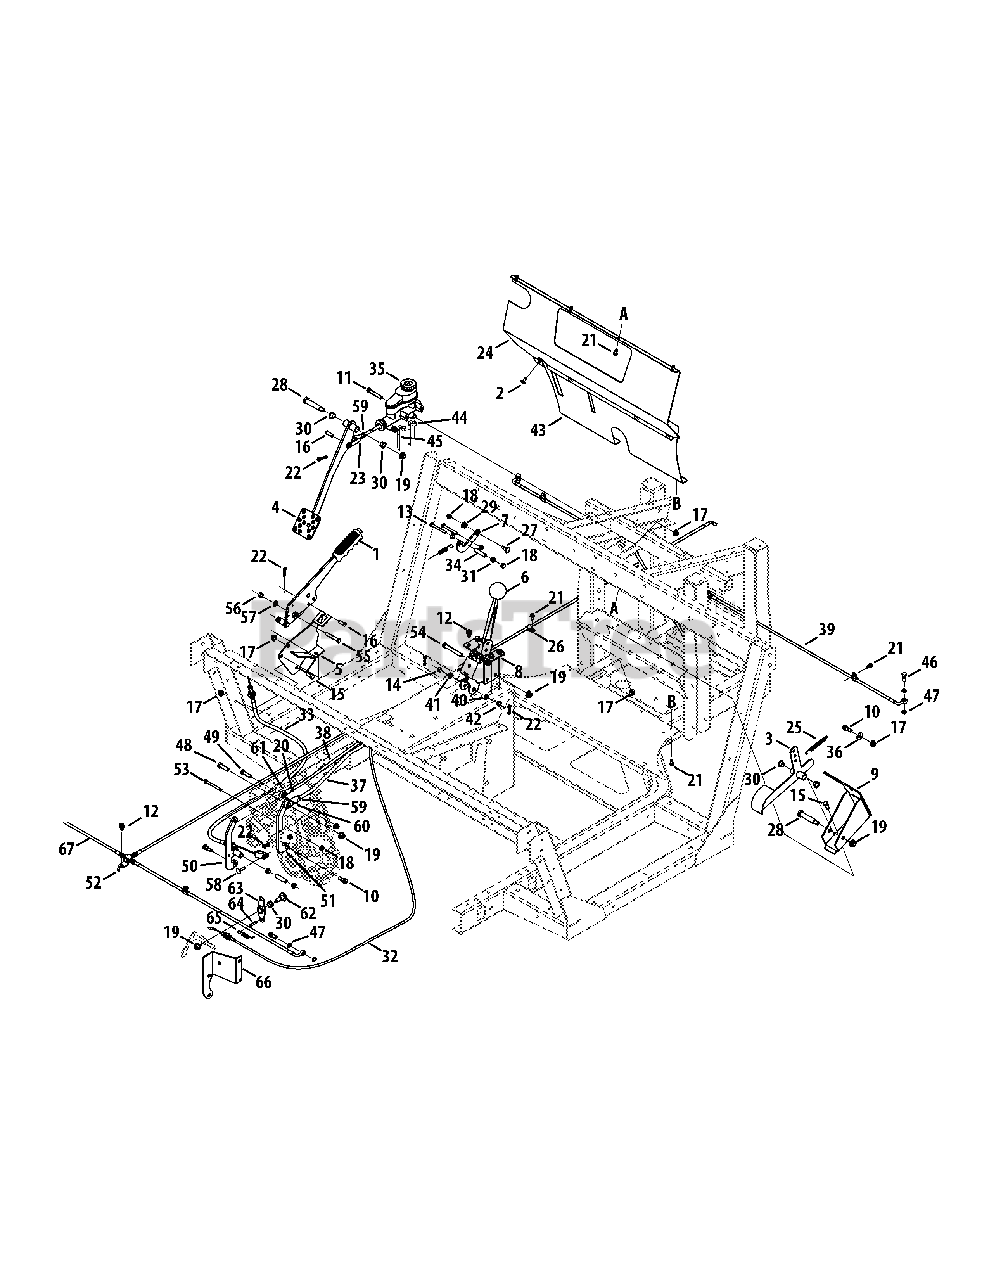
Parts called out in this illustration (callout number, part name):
1	Lever Assembly, Brake
2	Screw, ab, 1/4-14, 0.625,
3	Pedal Assembly, Accelerator
4	Pedal Assembly, Brake
5	Bracket Assembly, Park Brake
6	Shaft Assembly, Hurst, 4x4
7	Plate, Pawl, Over Center
8	Shaft, Console Mount
9	Bracket, Accelerator Pedal
10	Screw, Shldr, .372 x .375, 5/16-18
11	Screw, 5/16-18, 2.00, Gr5, Patch
12	Screw, Tt, 5/16-18, 0.500
13	Screw, 1/4-20, 2.25, Gr5, Std
14	Bearing., Flange, .315 ID
15	Screw, 5/16-18, .75, Gr5, Std
16	Pin, Clevis, 312 Od x 1.0"
17	Nut, Flange Lock, 5/16-18
18	Nut, Flange Lock, 1/4-20, Nylon
19	Nut, Flange Lock, 3/8-16, Nylon
20	Nut, Jam, 5/16-24, Gr5
21	Screw, Tt, 1/4-20 x .500
22	Pin, Cot, 3/32, 1.0
23	Yoke, 5/16-24
24	Panel, Dash, Upper
25	Spring, External, .49 Od x 3.15
26	Clamp, Hose
27	Screw, Shldr, .375x.380, 1/4-20
28	Screw, Shldr, .500 x 2.230, 3/8-16
29	Plastic Bushing .380 Id
30	Bearing, Flange, .500 x .34
31	Bearing, Flng., .375 x .580 x .250
32	Cable, Cont, Diff, Lock
33	Cable, Cont, Park, Brake, 4x4
34	Spacer, Pivot, Diff Lock
35	Cylinder, Master, Tandem
36	Washer, Flat, .349 x .879 x .063
37	Link, Shaft, F N R
38	Link, Shaft, Hi Lo, 4x4
39	Hose, brake, front
40	Washer, Flat, .385 x .62 x .063
41	Washer, Flat, .330 x .630 x .0635
42	Bearing, Flange, .377 Id
43	Panel, Dash, Lower, 4x4
44	Hose, Brake, Master Cyl, Front
45	Hose, Brake, Master Cyl, Rear
46	Fitting, Banjo Ftg Bolt, M10 x 1.00
47	Fitting, Banjo Ftg Crush Washer
48	Screw, 3/8-16 x 1.25
49	Screw, 5/16-18 x 1.25
50	Lever, Assembly, Shift, Hi-Lo, 4x4
51	Lever, Assembly, Shift, F N R
52	Fitting, Tee, -3, 45 Deg Flare
53	Screw, 1/4-20 x 2.50
54	Screw, 3/8-16 x 2.75
55	Screw, 5/16-18 x 2.00
56	Nut, Hex, 5/16-18
57	Washer, Flat, .344 x .688 x .065
58	Pin, Clevis
59	Nut, Jam, 3/8-24
60	Rod, End, 3/8 ID
61	Rod, End, 5/16 ID
62	Screw, shldr, .500 dia x .434
63	Lever, Assembly, Diff Lock
65	Spring, external, .38od x 2.10
66	Bracket, diff, Cable,mnt
67	Hose, brake, rear
